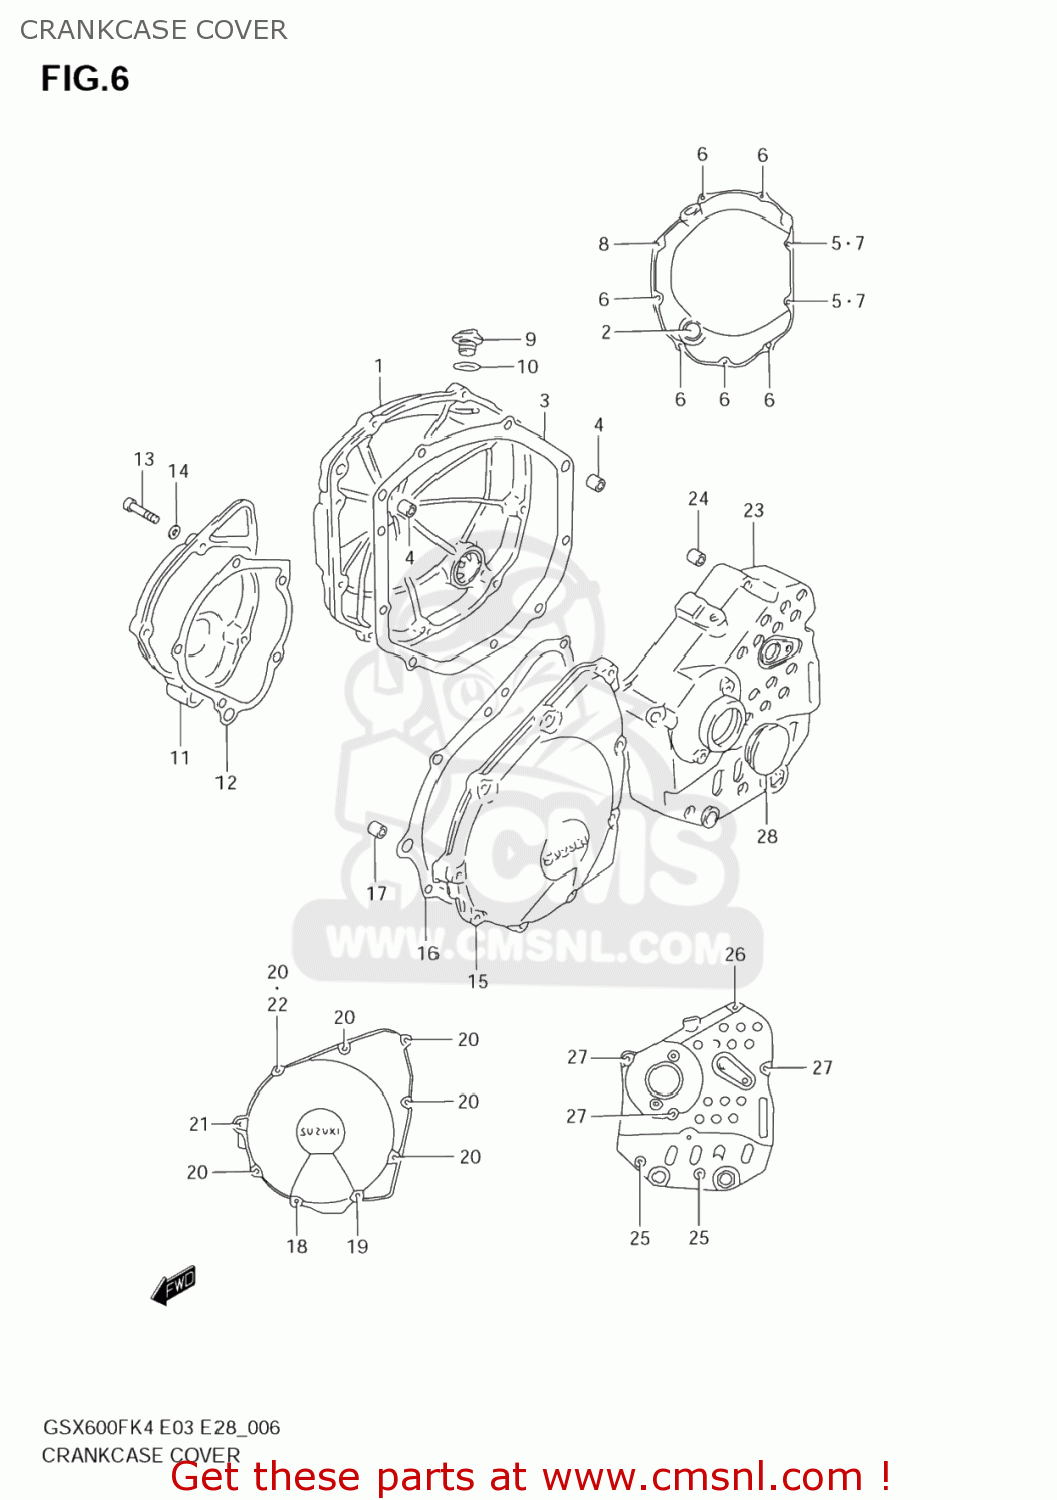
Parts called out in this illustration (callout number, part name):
1	COVER,CLUTCH
2	LENS,OIL LEVEL CHECK
3	GASKET,CL COVER (NAS)
4	PIN
5	GASKET(5.8X13X1.2) (NAS)
6	BOLT(6X25)
7	BOLT
8	BOLT
9	PLUG,ENGINE OIL FILLER
10	O RING(D:3.1,ID:16.8)
11	COVER,SIGNAL GENERATOR
12	GASKET,SIGNAL GEN COVER (NAS)
13	BOLT(6X22)
14	GASKET(5.8X13X1.2) (NAS)
15	COVER,STARTER GEAR
16	GASKET,STARTER GEAR COVER (NAS)
17	PIN(8.4X11X20)
18	BOLT(6X16)
19	BOLT(6X20)
20	BOLT(6X25)
21	BOLT
22	GASKET(5.8X13X1.2) (NAS)
23	COVER,ENGINE SPROCKET
24	PIN
25	BOLT
26	BOLT
27	BOLT
28	CAP(OD:36)
